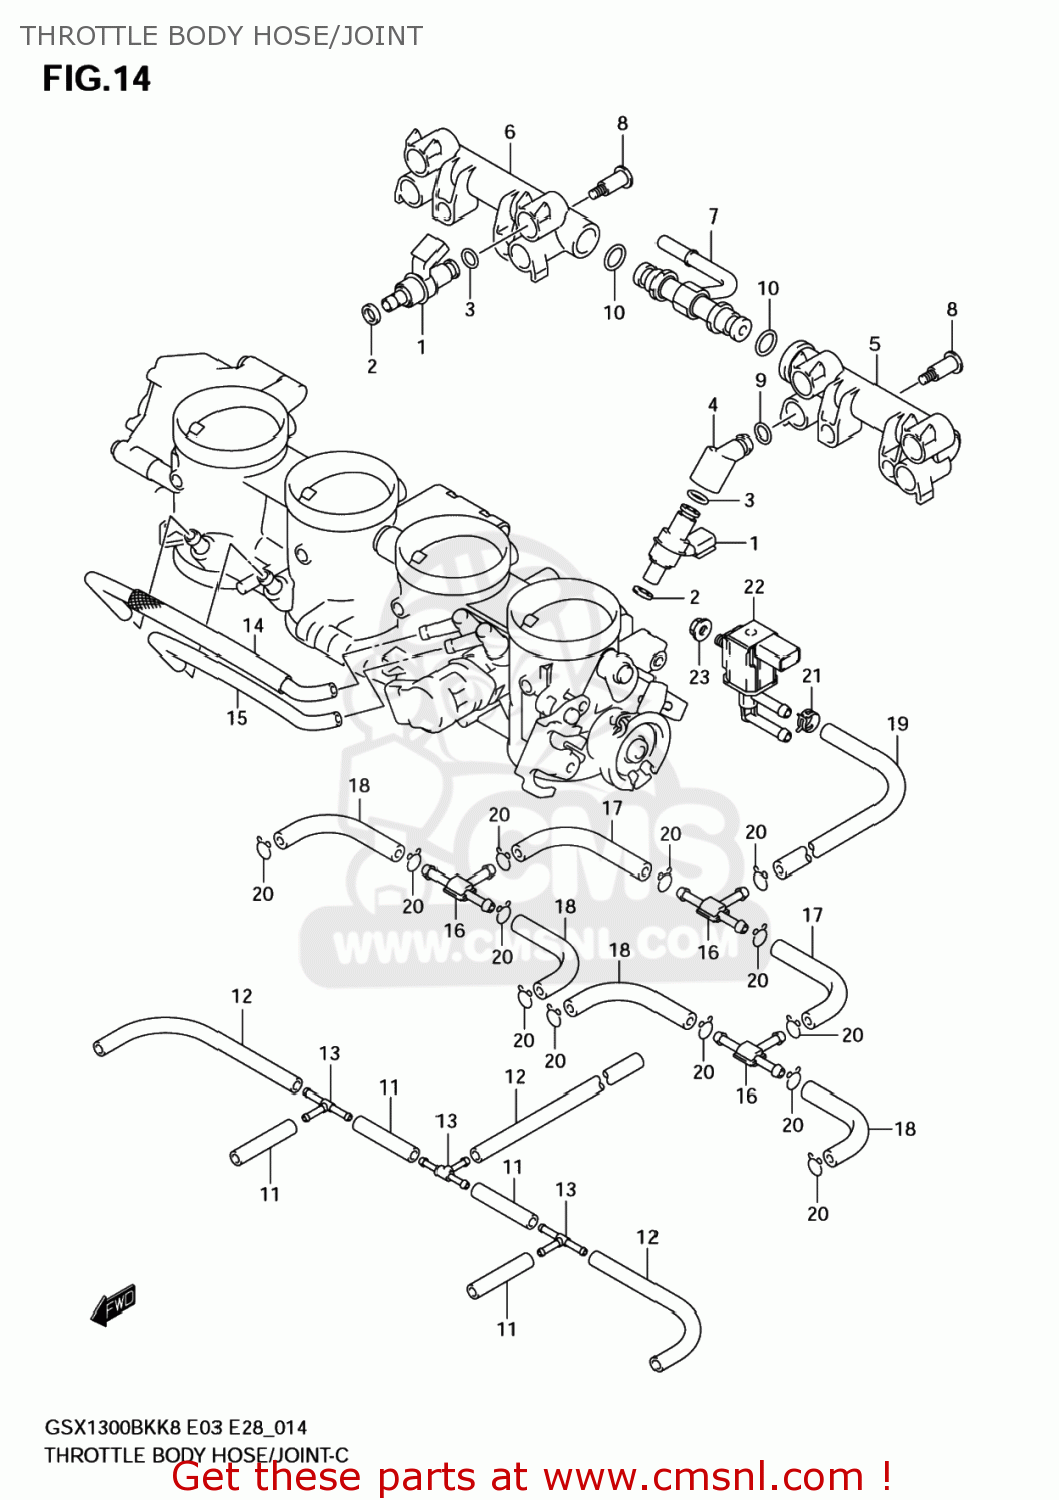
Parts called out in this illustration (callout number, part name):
1	INJECTOR ASSY
2	RING,SEAL
3	O RING
4	PIPE,FUEL
5	PIPE,FUEL
6	PIPE,FUEL
7	JOINT
8	SCREW
9	O RING
10	O RING
11	HOSE,RUBBER(L:35)
12	HOSE,RUBBER(L:100)
13	JOINT
14	TUBE
15	TUBE
16	JOINT
17	HOSE
18	HOSE
19	HOSE
20	CLIP
21	CLIP
22	VALVE,CANISTER PURGE
23	NUT
